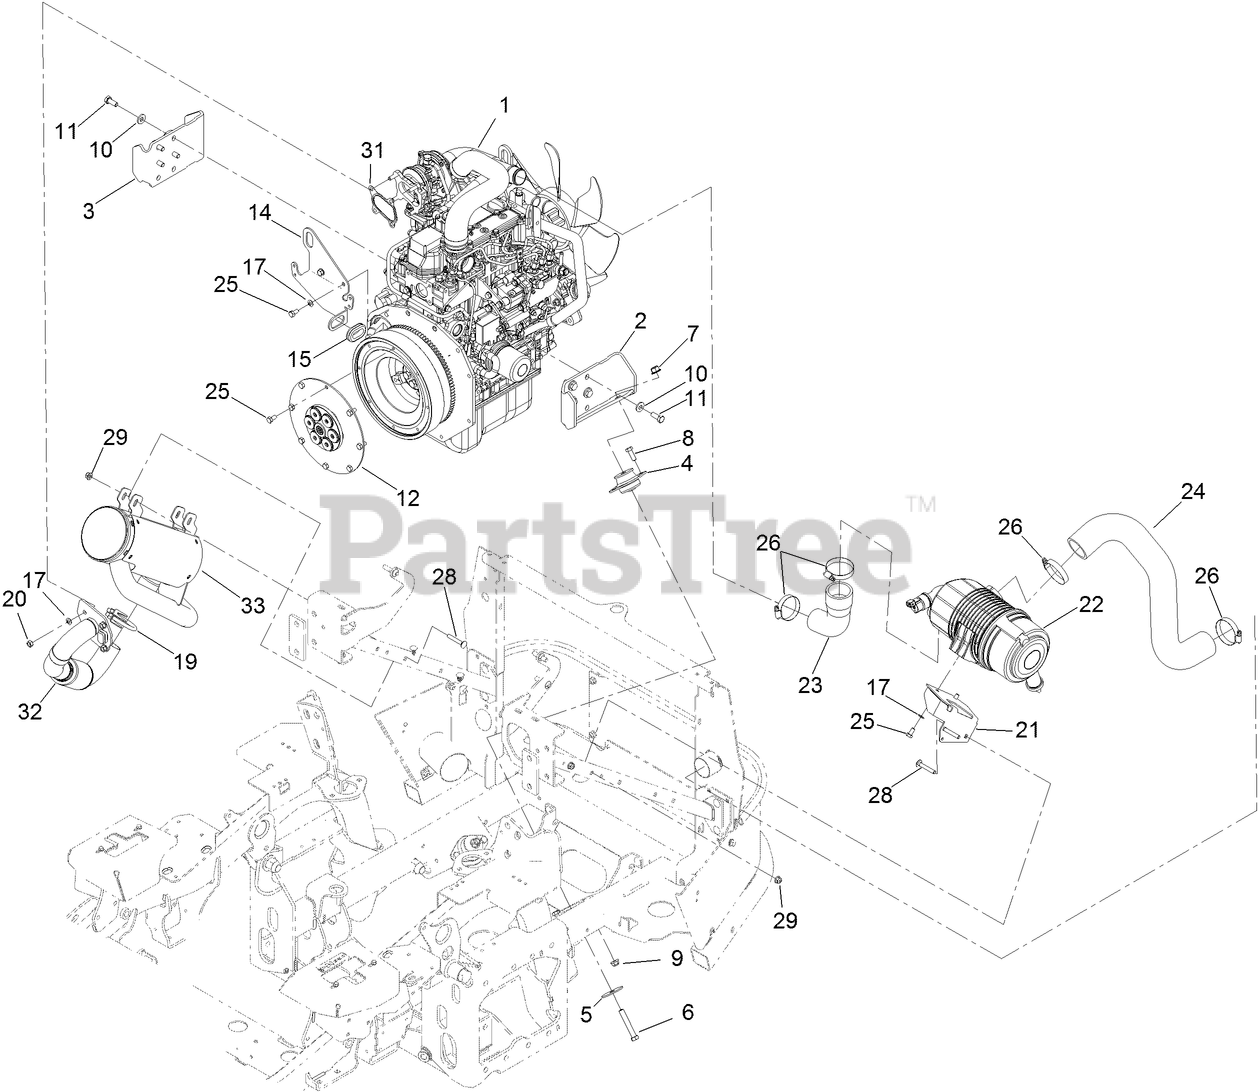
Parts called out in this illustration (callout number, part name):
1	ENGINE-YANMAR, 3TNV80FT-ZMTR1
2	MOUNT-ENGINE, LH
3	MOUNT-ENGINE, RH
5	WASHER-SNUBBING
6	SCREW-HH
7	NUT-HF, NI
8	SCREW-HH
9	NUT-HF, NI
10	WASHER-BELLEVILLE
11	SCREW-HH
12	COUPLER-FLYWHEEL
14	BRACKET-GUIDE
15	GROMMET
17	WASHER-BELLEVILLE
19	CLAMP
20	NUT-HEX
21	BRACKET-CLEANER, AIR
22	AIR CLEANER ASM
23	HOSE-AIR
24	HOSE-AIR
25	BOLT
26	CLAMP-HOSE
28	BOLT-CARR
29	NUT-HF, NI
31	GASKET-HEADER
32	HEADER PIPE
33	MUFFLER
